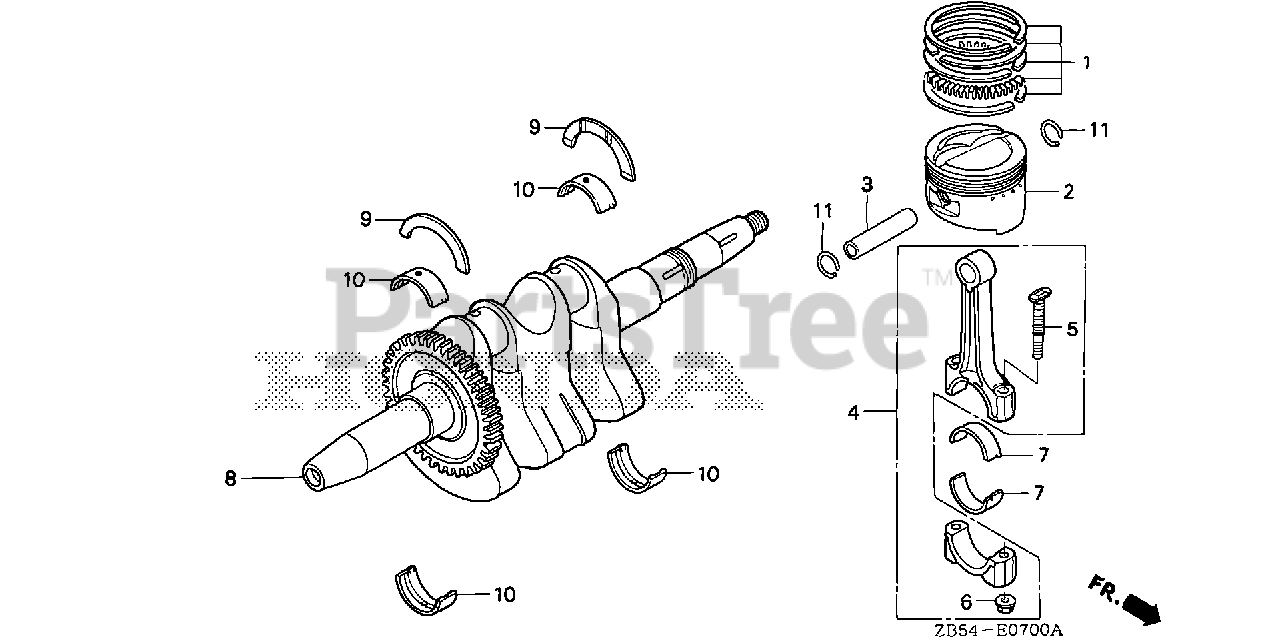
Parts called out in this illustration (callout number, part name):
1	RING SET, PISTON (STD) (RIKEN)
1	RING SET, PISTON (0.25) (RIKEN)
1	RING SET, PISTON (0.25) (TEIKOKU)
1	RING SET, PISTON (0.50) (TEIKOKU)
2	PISTON (STD)
2	PISTON (0.25)
2	PISTON (0.50)
3	PIN, PISTON
4	ROD ASSY., CONNECTING
5	BOLT, CONNECTING ROD
6	NUT, CONNECTING ROD
7	BEARING A, CONNECTING ROD (BLACK)
7	BEARING B, CONNECTING ROD (BROWN)
7	BEARING C, CONNECTING ROD (GREEN)
7	BEARING D, CONNECTING ROD (YELLOW)
7	BEARING E, CONNECTING ROD (RED)
8	CRANKSHAFT
9	BEARING, CRANKSHAFT THRUST
10	BEARING, CRANKSHAFT (BLACK)
10	BEARING, CRANKSHAFT (BROWN)
10	BEARING, CRANKSHAFT (GREEN)
10	BEARING, CRANKSHAFT (YELLOW)
10	BEARING, CRANKSHAFT (RED)
11	CLIP, PISTON PIN (14MM)
